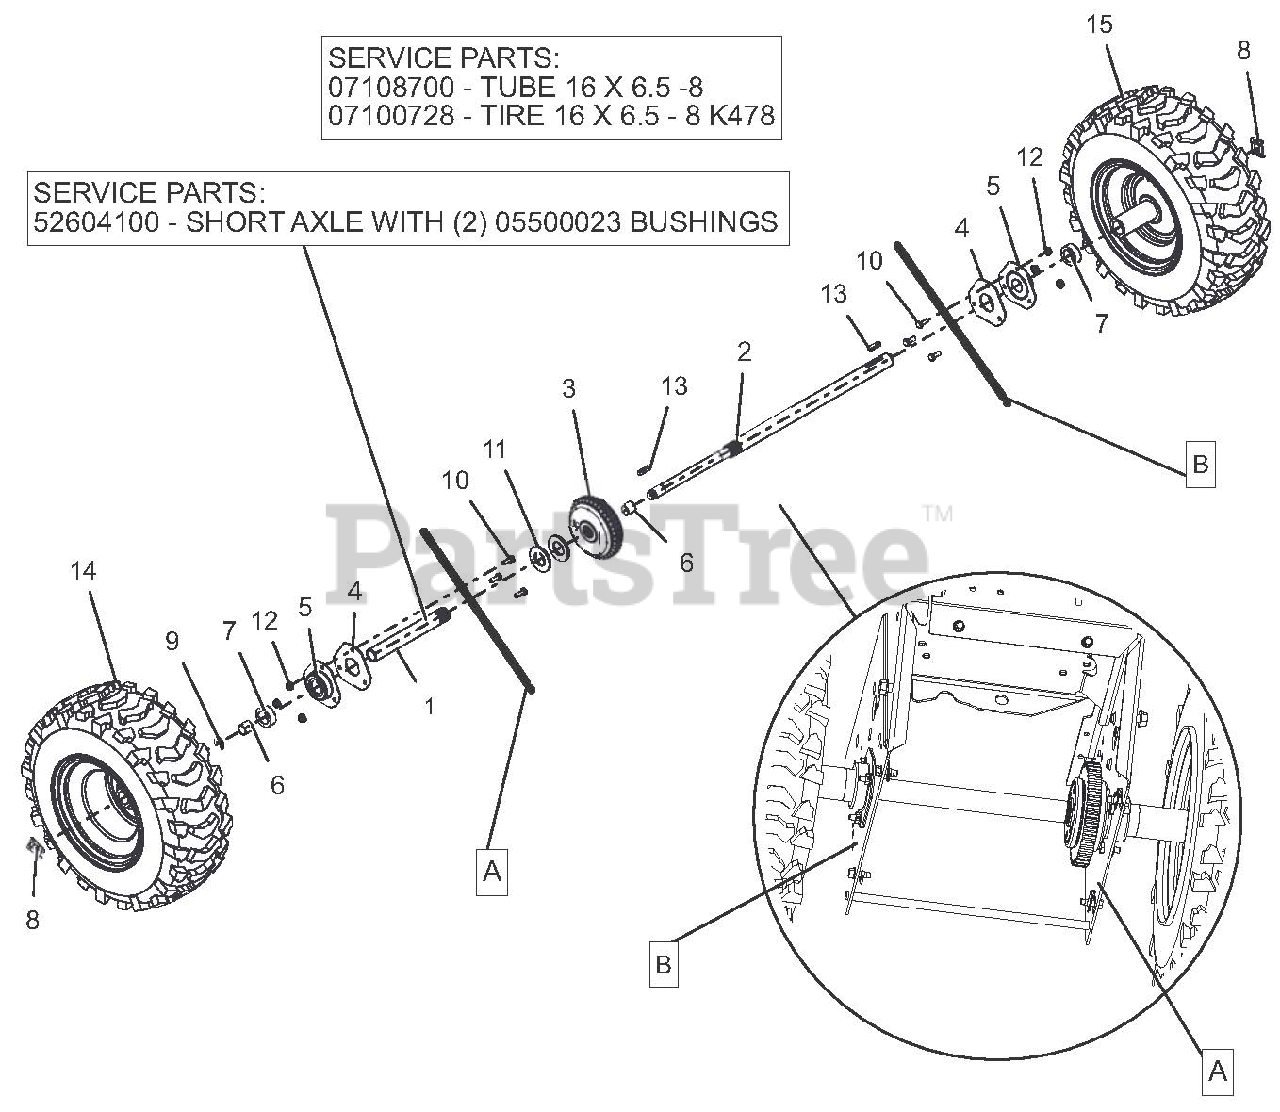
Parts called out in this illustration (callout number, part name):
1	AXLE, SHORT - PRO AUTO DIFF
1	SHORT AXLE
1	BSHG-SLV .706X.764X.75 BRZ
2	AXLE, LONG - PRO AUTO DIFF
3	DIFFERENTIAL, AUTOMATIC
4	PLATE, BEARING SPACER (BLACK)
5	BRG, FLANGE 1.003/1.000 3 BOLT
6	BSHG, SLV .706 X .764 X .75 BRZ
7	SPACER, PRO AXLE BEARING
8	CLIP, SNAP - .625
9	RING, RETAINING-E .625X.042
10	BLT-HEX .25-20X.75 GR5 YWZC
11	WSHR-FL-STL1.062X2.00X.134YWZC
12	NUT, LK-CTR-FLG .25-20 YWZC
13	KEY, RECT .25X.188X1.00
14	TIRE/WHEEL, RH 16X6.50-8 DIFF
15	TIRE/WHEEL, LH 16X6.50-8 DIFF
16	TUBE 16 X 6.5-8
17	TIRE 16 X 6.5-8 K478
